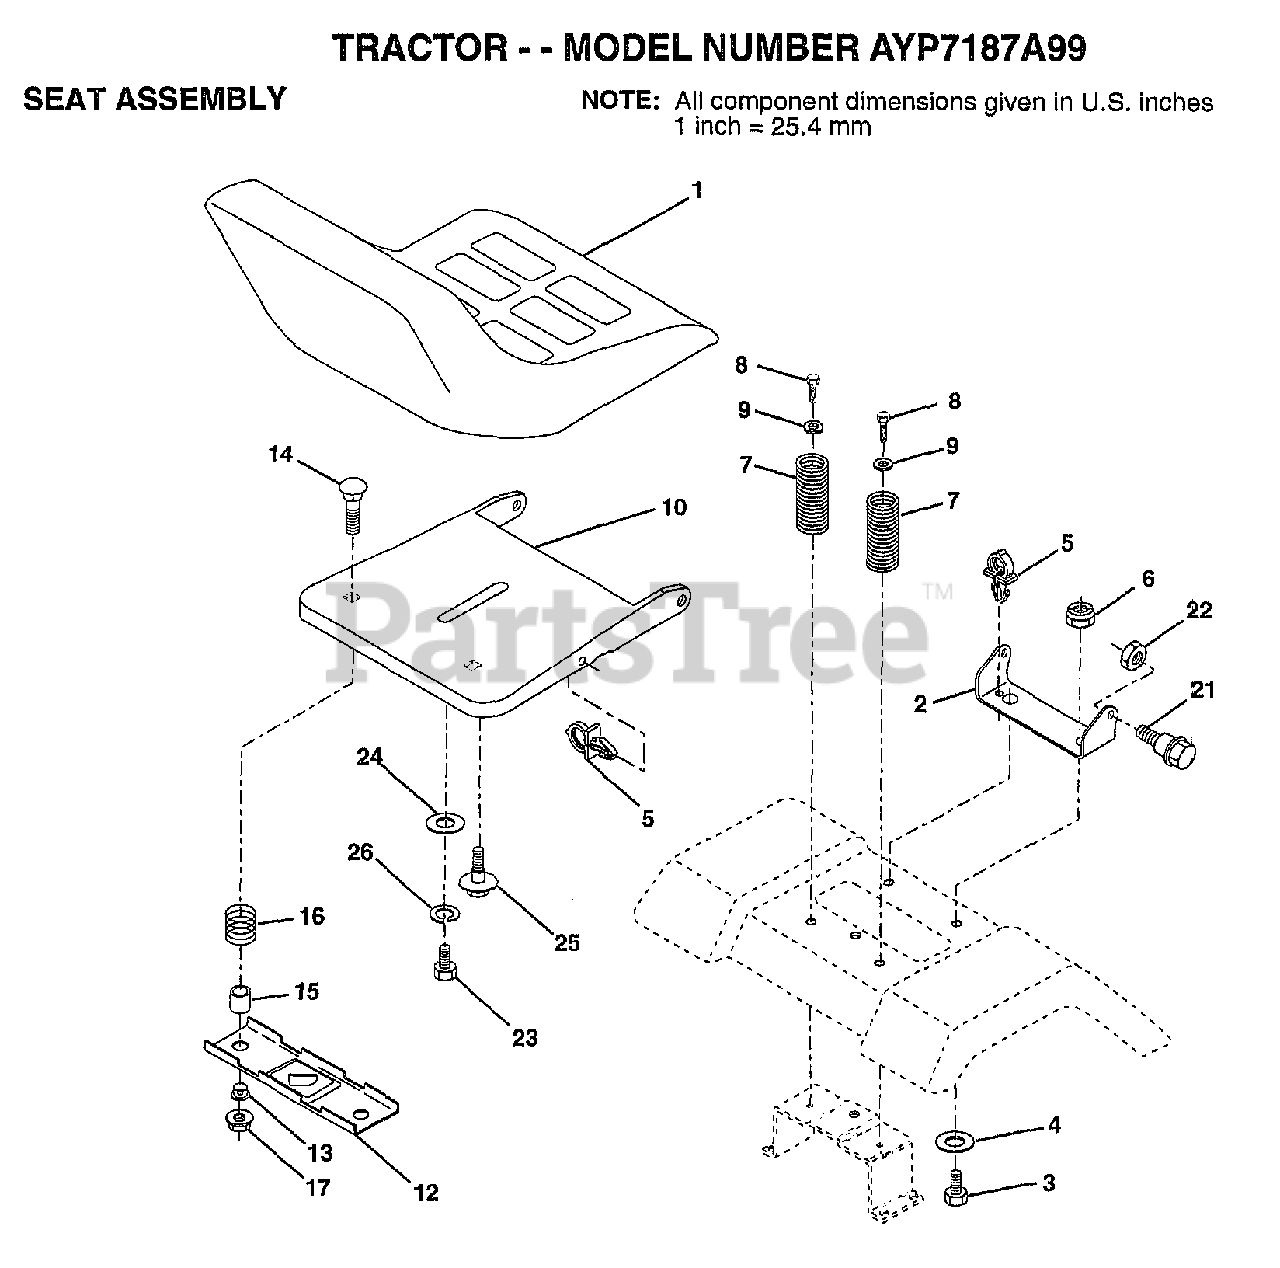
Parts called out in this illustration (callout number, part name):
1	SEAT.2400/1416.BK
2	BRACKET PVT SEAT
3	BOLT
4	WASHER PM
5	CLIP.PUSH-IN.HING
6	NUT
7	SPRING COMPRESSIO
8	SCREW GTV
9	WASHER
10	PAN-SEAT
12	BRKT SWITCH
13	BUSHING
14	BOLT-RD HD SQ NK
15	SPLIT SPACER
16	SPRING
21	"BOLT,SHOULDER"
22	NUT
23	BOLT
24	WASHER
25	"BOLT,SHOULDER"
26	LOCKWASHER
